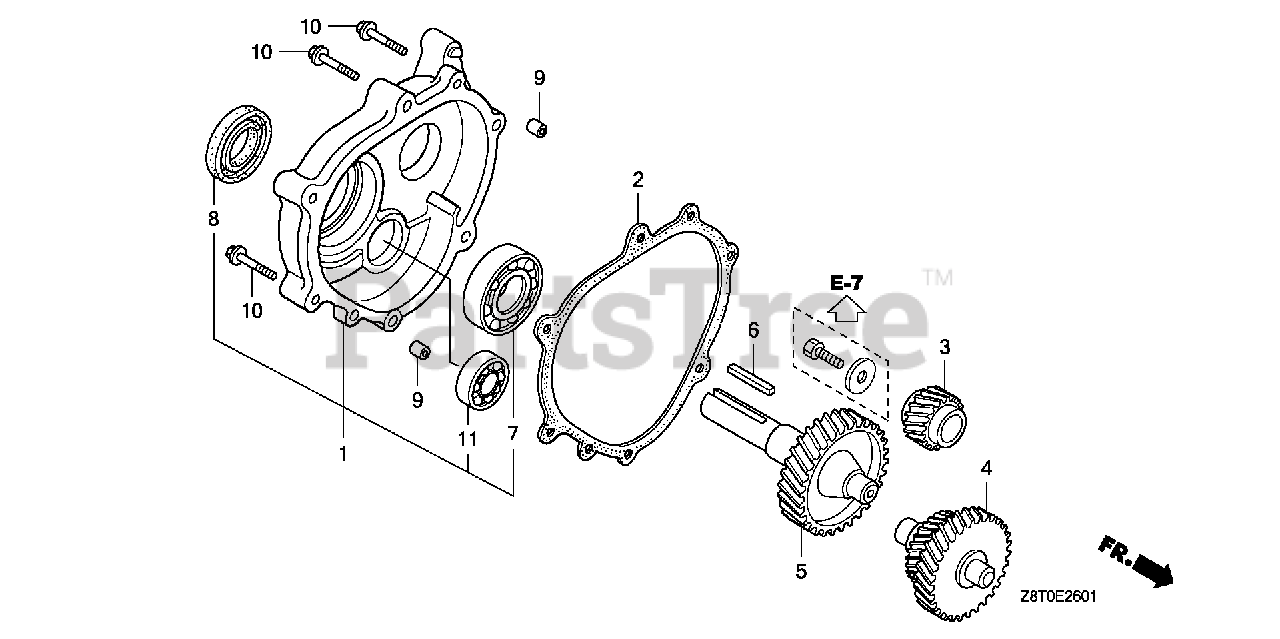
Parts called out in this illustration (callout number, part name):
1	COVER ASSY., GEAR CASE
2	GASKET, CHAIN CASE COVER
3	GEAR, PRIMARY DRIVE (12T)
4	COUNTERSHAFT (13T/27T)
5	SHAFT, P.T.O. (34T)
6	KEY (6.3X6.3X43)
7	BEARING, RADIAL BALL (6206) (NTN)
8	OIL SEAL (30X46X8) (NOK ASIA)
9	PIN, DOWEL (8X14)
10	BOLT, FLANGE (8X40)
11	BEARING, RADIAL BALL (6302)
